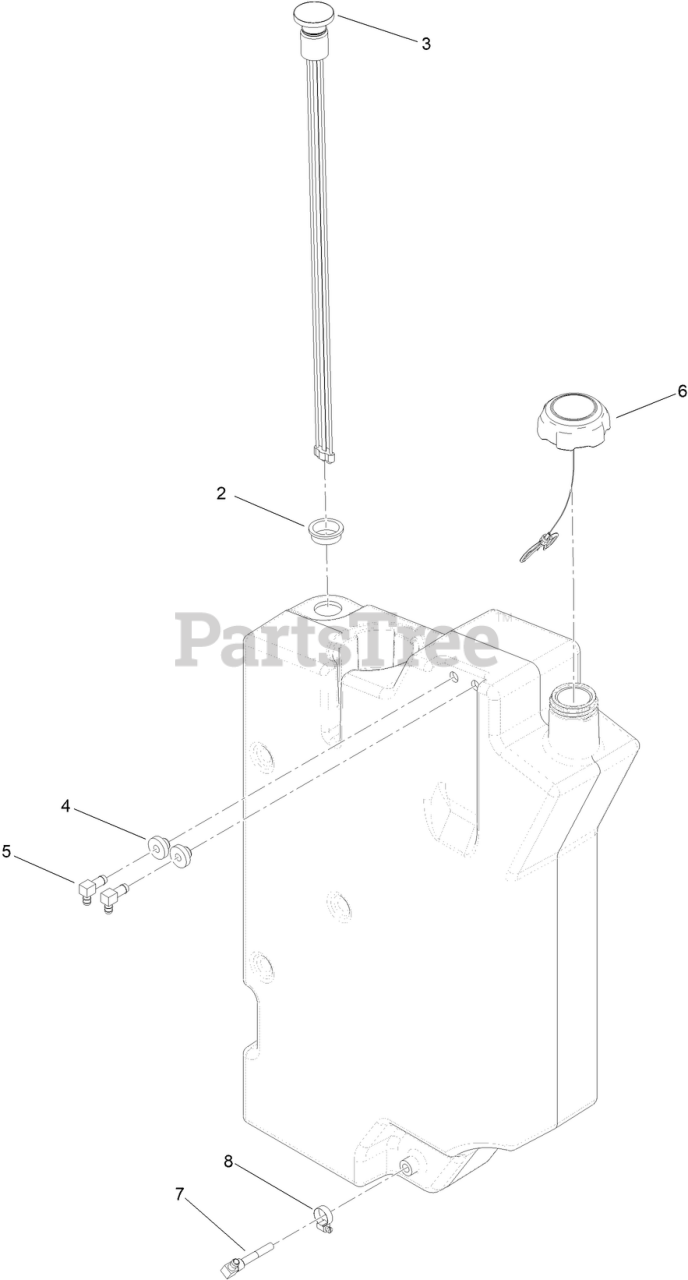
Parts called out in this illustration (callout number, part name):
2	GROMMET
3	GAUGE-LEVEL, FUEL
4	BUSHING
5	FITTING-ELBOW, 90 DEG
6	CAP-DIESEL
7	PIPE-STAND
8	CLAMP-HOSE
